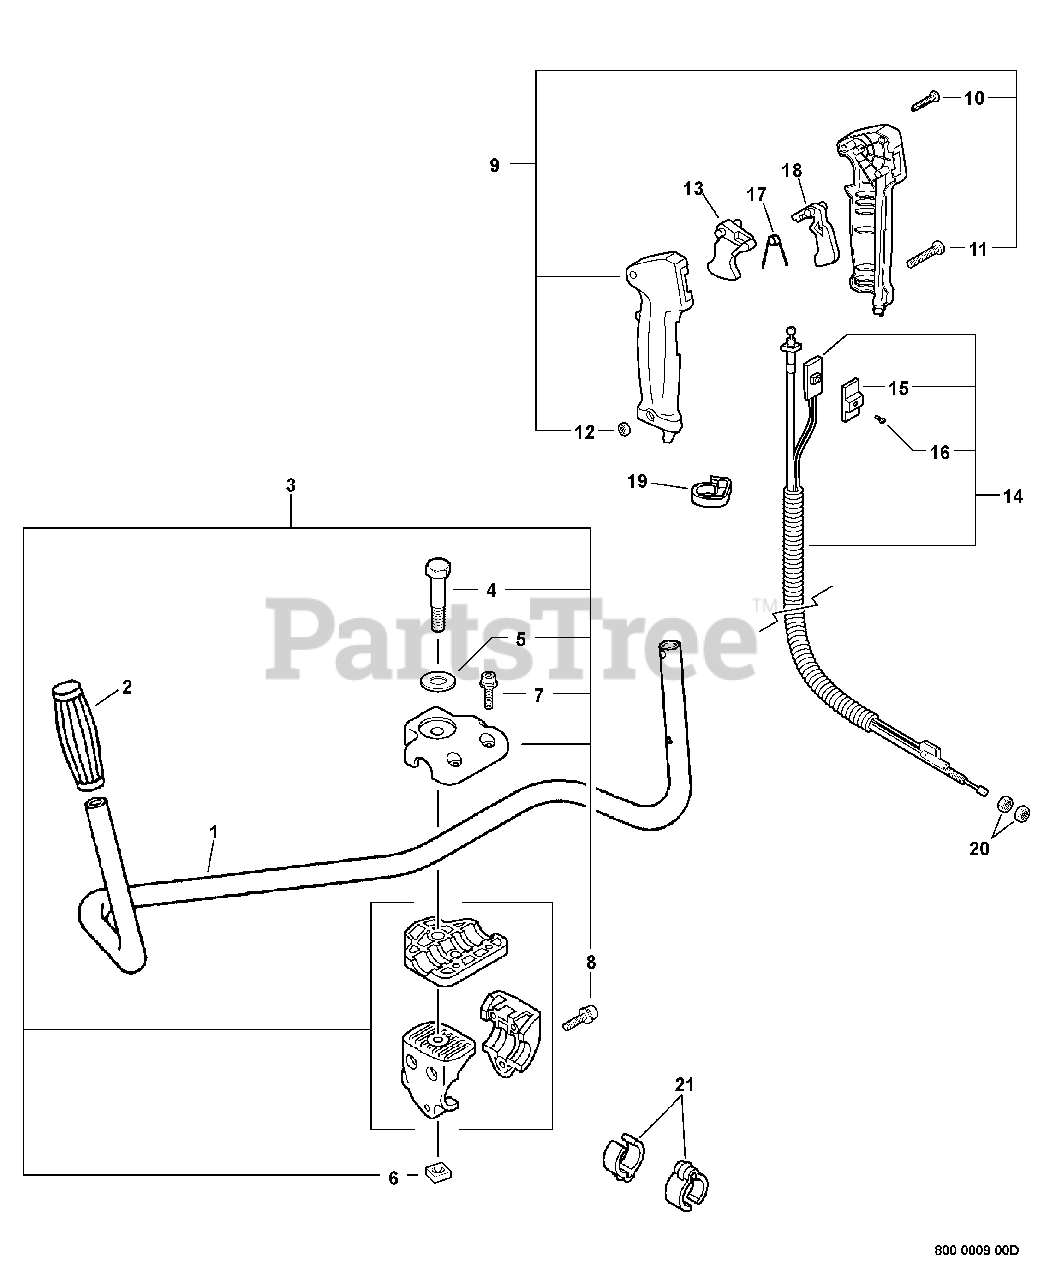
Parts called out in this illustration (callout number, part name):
1	HANDLEBAR
2	GRIP, HANDLE
3	BRACKET KIT, HANDLEBAR
4	BOLT 8×55
5	WASHER 8
6	NUT 8×1.25
7	BOLT 5×20
8	BOLT 5×30
9	CONTROL HANDLE KIT
10	SCREW 3×25
11	SCREW 5×30
12	NUT M5
13	TRIGGER, THROTTLE
14	CONTROL CABLE ASSY
15	KNOB, SWITCH - ORANGE
16	SCREW 3×10
17	SPRING, TORSION
18	LOCKOUT, THROTTLE
21	CLIP, CABLE 25 MM
